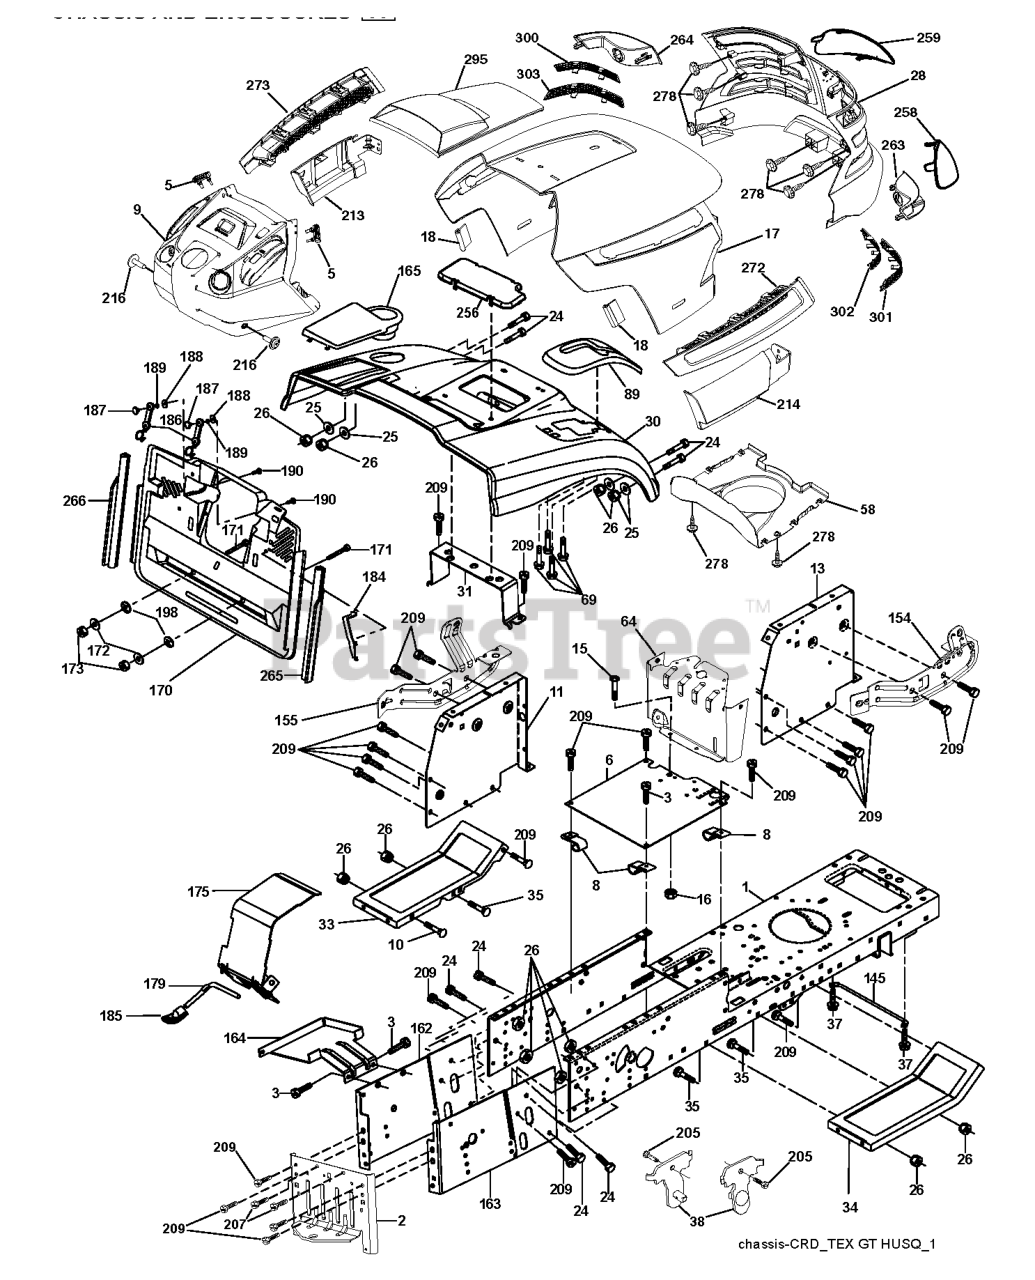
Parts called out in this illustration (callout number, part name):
2	DRAWBAR
3	SCREW 3/8-16X3/4
5	BUMPER DASH
6	PLATE
8	CLIP,INSULATOR
10	BOLT D
11	PANEL DASH LH
13	PANEL DASH RH
15	Screw, Machine, Truss Head 5/16-18 UNC x 3/4
16	NUT
17	HOOD
18	BUMPER.HOOD.TEX.HUSQVARNA
25	WASHER
26	NUT
28	GRILL.ASM.HUSQ.TG/CRD.W/TRIM
30	CONSOLE.CRD.AUTO.GRY
31	BRACKET SUPPORT FENDER
33	FOOTREST PNT LH
34	FOOTREST PNT RH
37	Screw 5/16-18 x 1/2 Hex, Self Tapping 5/16-18 x 1/2
38	BRACKET ASM PIVOT MOWER REAR
58	AIR.DUCT.TEXGT.HUSQ.31
69	SCREW.HI-LO.CONSOLE
89	CONSOLE.CRD.AUTO.GREY.2005
145	ROD.PIVOT.HOOD
162	BRACKET
163	BRACKET EXTEN CHASSIS RH CRD
165	RP.COVER.BATTERY.CRD.GREY
172	WASHER
175	DOOR TRAP
179	ROD PIVOT FBI
184	BRACKET.ACTUATOR.BAGGER.SRD
186	LATCH ASSY
187	WELDNUT
189	LOCKWASHER #10
190	SCREW
207	SCREW, 5/16-18 X 1/2
209	SCREW, 3/8-16X3/4
213	SKIRT.HOOD.SIDE.HUSQ.LH.GREY
214	SKIRT.HOOD.SIDE.HUSQ.RH.GREY
216	SCREW 14-20 X 5/8
256	COVER FENDER CRD
258	LENS.RH.TEX.GT.HUSQ.CL
259	LENS.LH.TEX.GT.HUSQ.CL
263	BEZEL.RH.TEX.GT.HUSQ
264	BEZEL.LH.TEX.GT.HUSQ
265	SEALING
266	SEALING
272	VENT.SIDE.HOOD.HUSQ.RH.GREY
273	VENT.SIDE.HOOD.HUSQ.LH.GRAY
278	SCREW.#10 X 0.750.BOS
295	VENT.ASM.TORPHD.HUSQGT.LOGO.CL
300	INSERT.HEX.GRILL.HUSQ.
301	INSERT.HEX.GRILL.HUSQ.GREY
302	INSERT.HEX.GRILL.HUSQ.
303	INSERT.HEX.GRILL.HUSQ.
